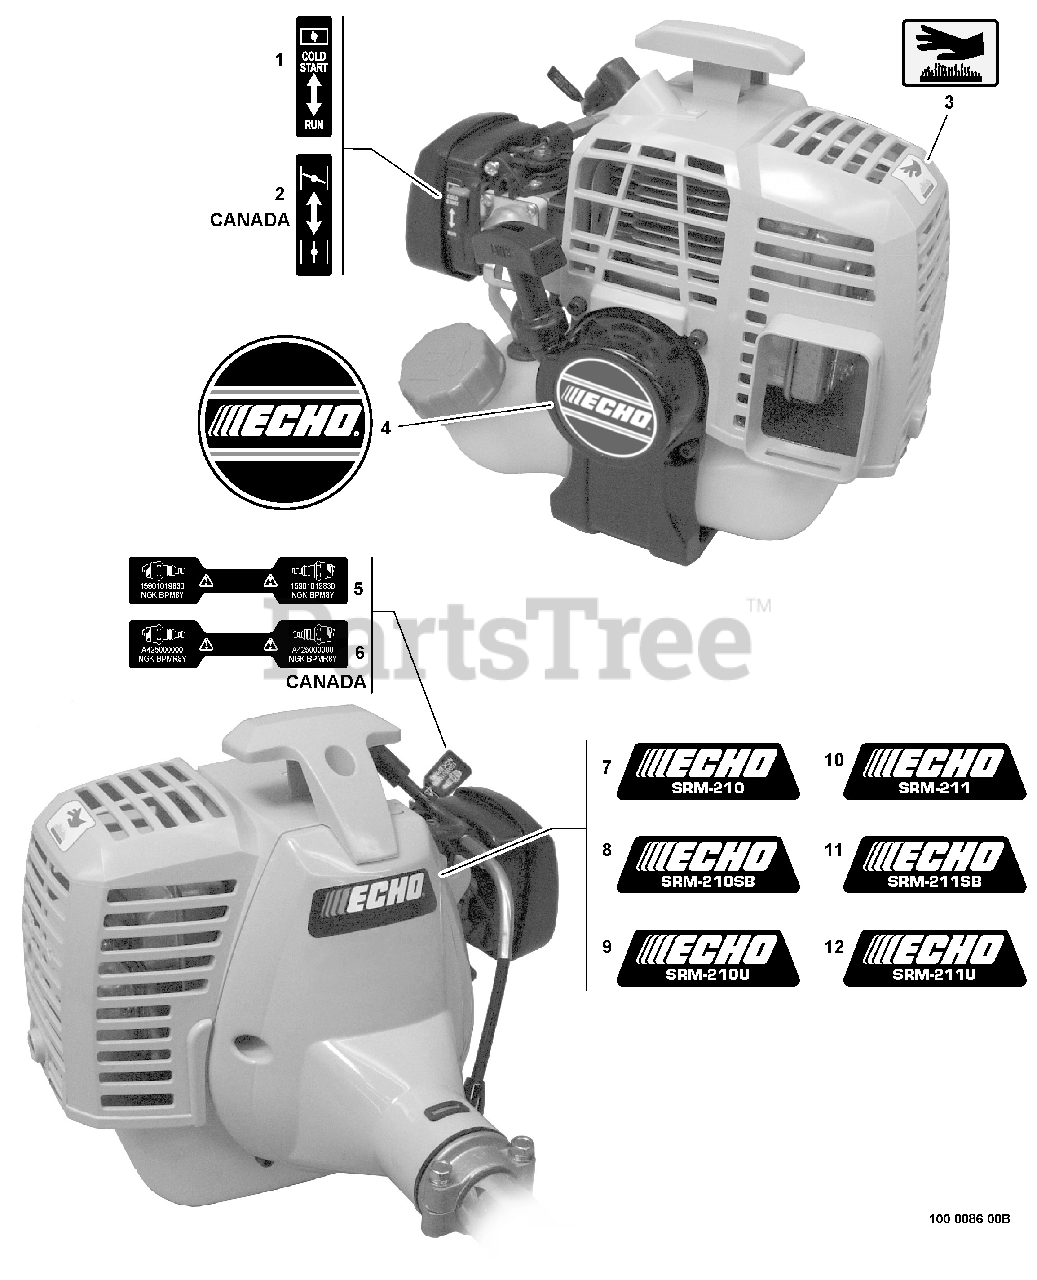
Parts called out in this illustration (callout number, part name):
1	LABEL - CHOKE
2	LABEL - CHOKE
3	LABEL - HOT SURFACE
4	LABEL - ECHO
5	LABEL - SPARK PLUG -- BPM-8Y
6	LABEL - SPARK PLUG -- BPMR-8Y
7	LABEL - MODEL SRM-210
8	LABEL - MODEL SRM-210SB
9	LABEL - MODEL SRM-210U
10	LABEL - MODEL SRM-211
11	LABEL - MODEL SRM-211SB
12	LABEL - MODEL SRM-211U
